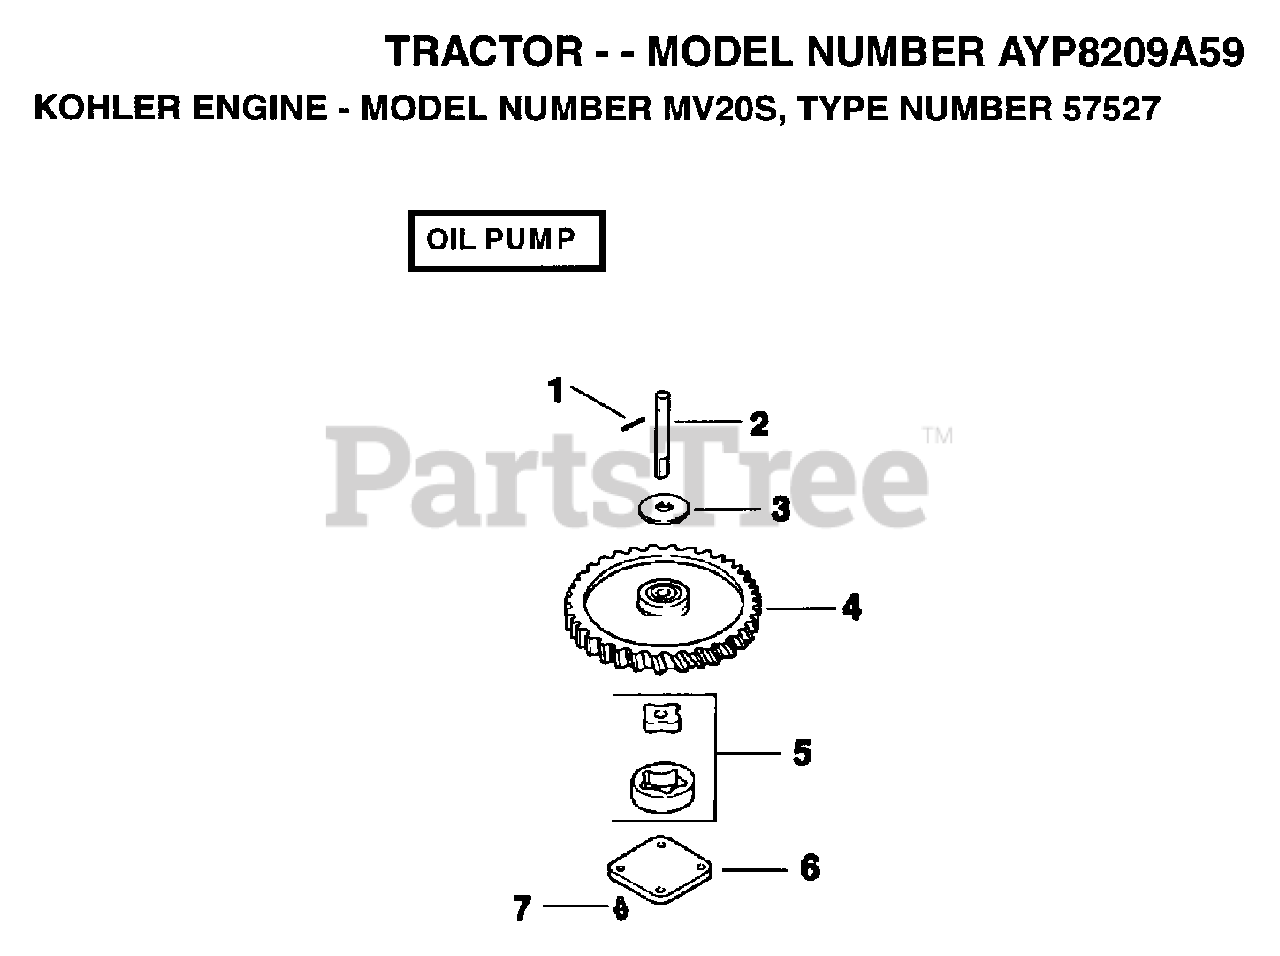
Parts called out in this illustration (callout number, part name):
1	PIN, ROLL
2	SHAFT OIL PUMP
4	GEAR OIL PUMP
6	COVER OIL PUMP
7	SCREW
